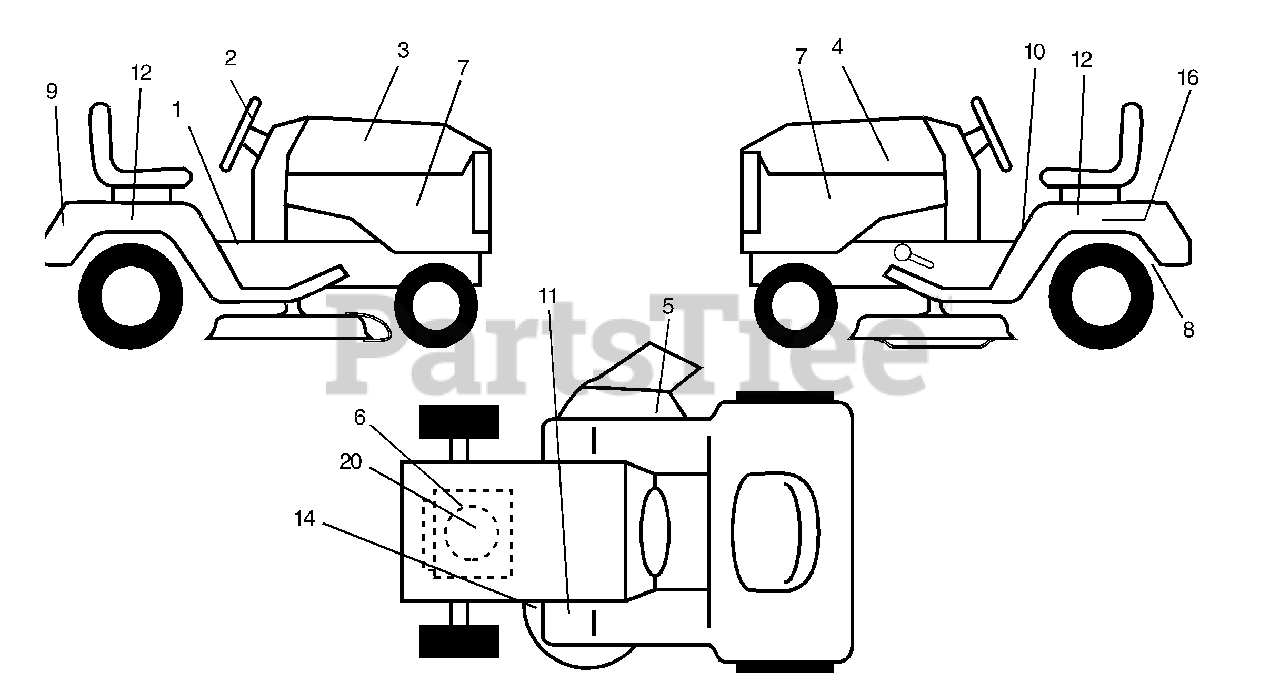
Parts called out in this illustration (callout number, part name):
1	Decal Instruction Operat English
2	Decal Ins Strg Wh
3	Decal Hood Rh
4	Decal Hood Lh
5	Decal Deck
6	Decal Engine
7	Decal Panel Side
8	Decal Chassis Disconnect
9	Decal Fender Logo
10	Decal Danger English
11	Decal Clutch/brake English
12	Decal Fender
14	Decal V-belt Schematic 42"
16	Decal Battery Danger/Poison
20	Decal HP Engine
